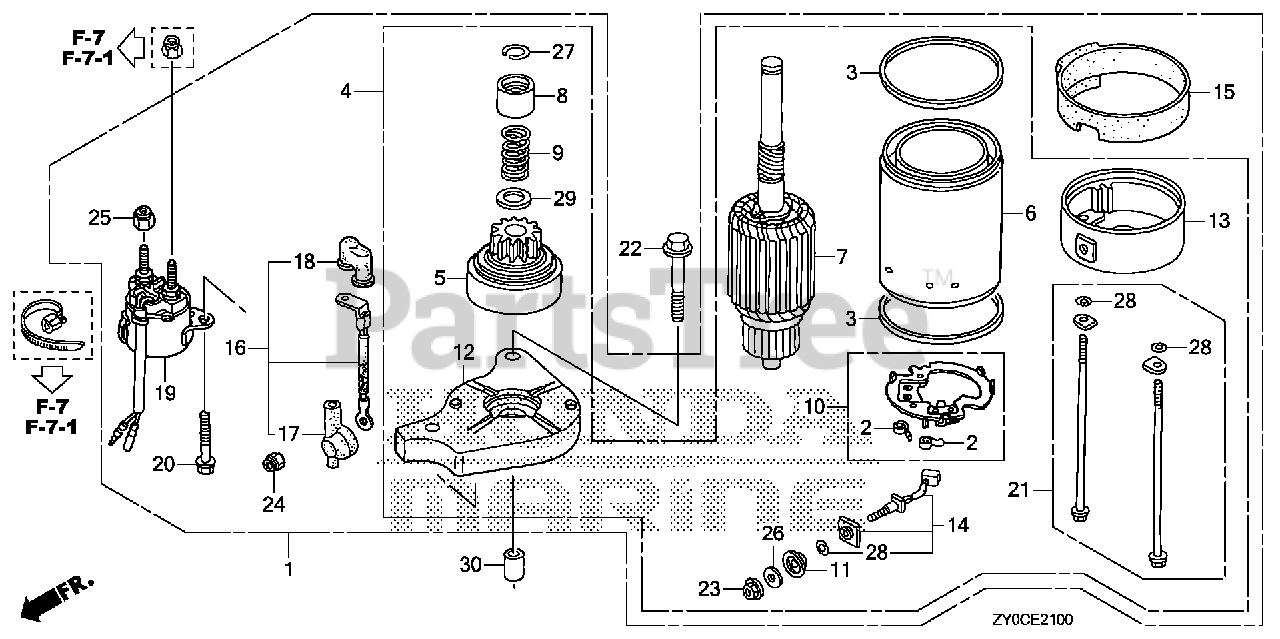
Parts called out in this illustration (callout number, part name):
1	MOTOR ASSY., STARTER
2	SPRING, CARBON BRUSH
4	MOTOR UNIT, STARTER
8	PIECE, STOPPER
9	SPRING, RETURN
10	HOLDER, BRUSH
12	BRACKET, FR.
13	BRACKET, RR.
14	UNIT, TERMINAL
15	SUSPENSION, STARTER
16	WIRE, MAGNETIC SWITCH
17	COVER, STARTER TERMINAL
18	COVER, MAGNETIC SWITCH TERMINAL
19	SWITCH ASSY., STARTER MAGNETIC
20	BOLT, FLANGE (6X14)
21	BOLT SET, SETTING
22	BOLT, FLANGE (8X45)
23	NUT-WASHER (6MM)
24	NUT, LOCK (6MM)
25	NUT, LOCK (6MM)
26	WASHER (6MM)
27	CIRCLIP (14MM)
28	O-RING
30	PIN, DOWEL (10X12)
